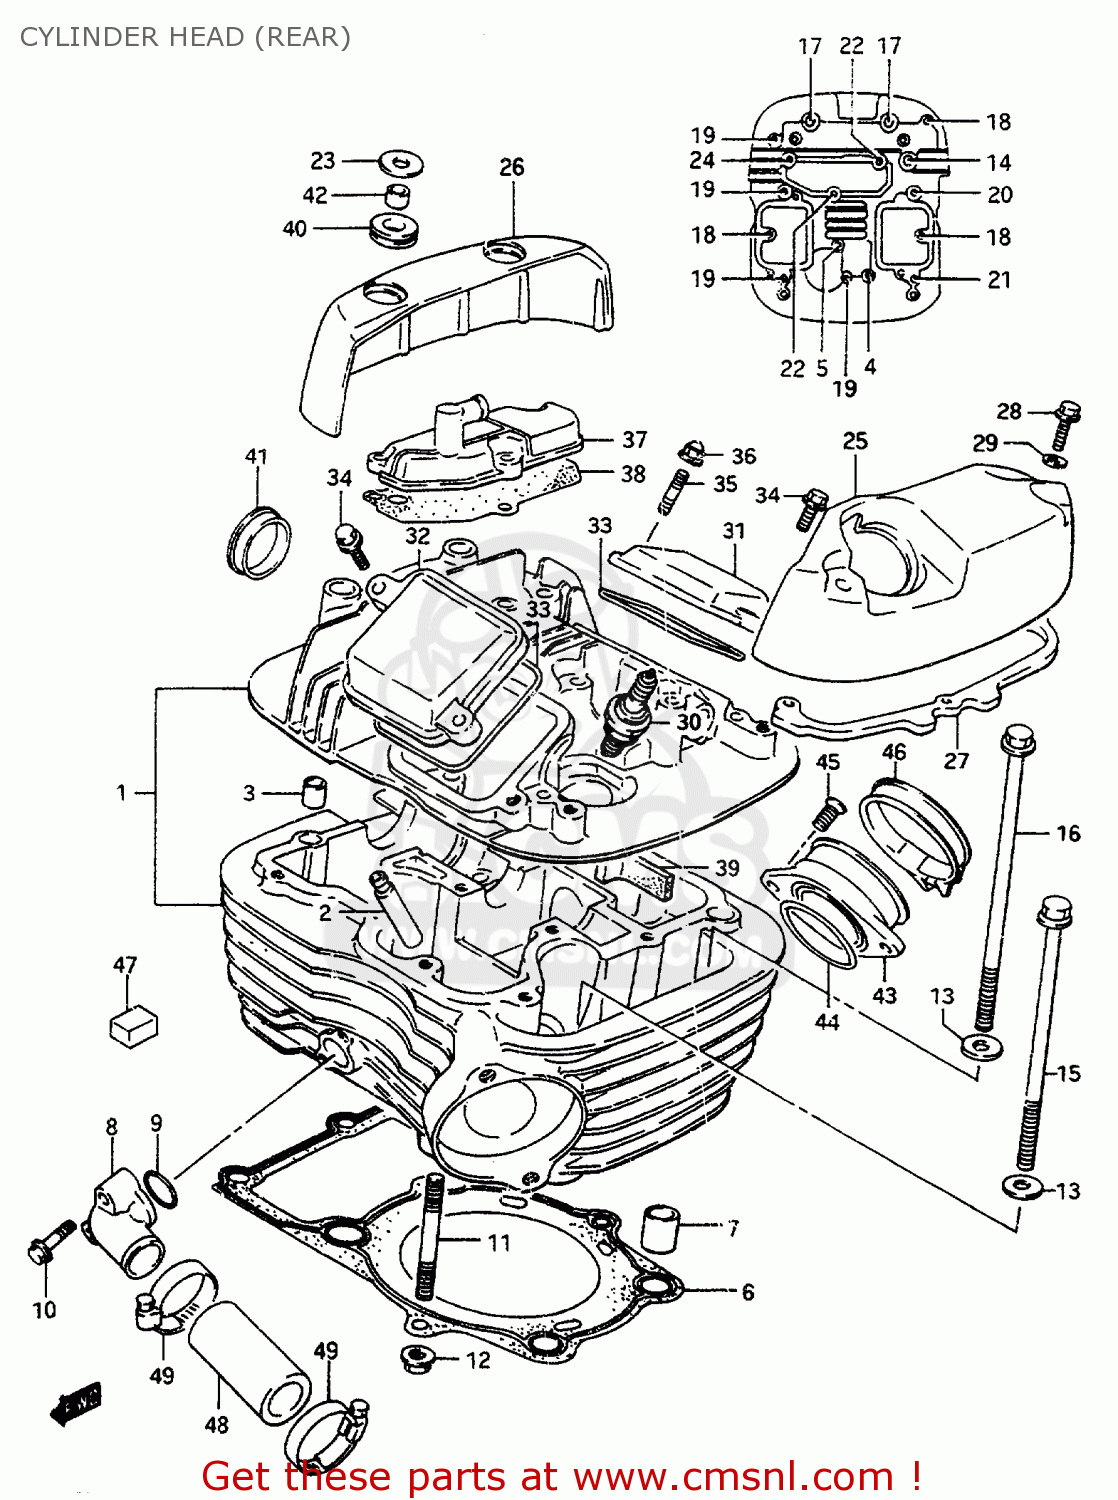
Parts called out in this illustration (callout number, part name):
1	HEAD ASSY,CYLINDER RR
2	GUIDE,VALVE
3	PIN(8.4X11X14)
4	BOLT(6X50)
5	BOLT(6X55)
6	GASKET,CYLINDER HEAD RR (NAS)
7	PIN
8	UNION,CYLINDER HEAD WATER
9	O RING(D:2.4,ID:17.8)
10	BOLT
11	BOLT,STUD
12	NUT
13	WASHER (10.5X22X2.3)
14	BOLT(8X140)
15	BOLT(10X155)
16	BOLT(10X165)
17	BOLT(8X245)
18	BOLT
19	BOLT
20	BOLT
21	BOLT
22	BOLT(6X55)
23	WASHER (8.2X24X1.6)
24	BOLT
25	CAP,CYLINDER HEAD COVER RR,L
26	CAP,CYLINDER HEAD COVER RR,R
27	CUSHION,RR,L CAP
28	BOLT
29	WASHER
30	PLUG,SPARK(DPR8EA-9)
31	CAP,INSP.INT
32	CAP,INSPECTION,EXHAUST
33	GASKET,INSPECTION CAP (NAS)
34	BOLT
35	STUD 6X16
36	NUT
37	COVER,BREATHER
38	GASKET,BREATHER COVER (NAS)
39	PLATE,HEAD COVER RR
40	CUSHION
41	PLUG(OD:30)
42	BUSH
43	PIPE COMP,INTAKE,REAR
44	O-RING (D:2.4 ID:39.7)
45	SCREW
46	CLAMP
47	PAD
48	HOSE,CYLINDER HEAD JOINT
49	CLAMP
